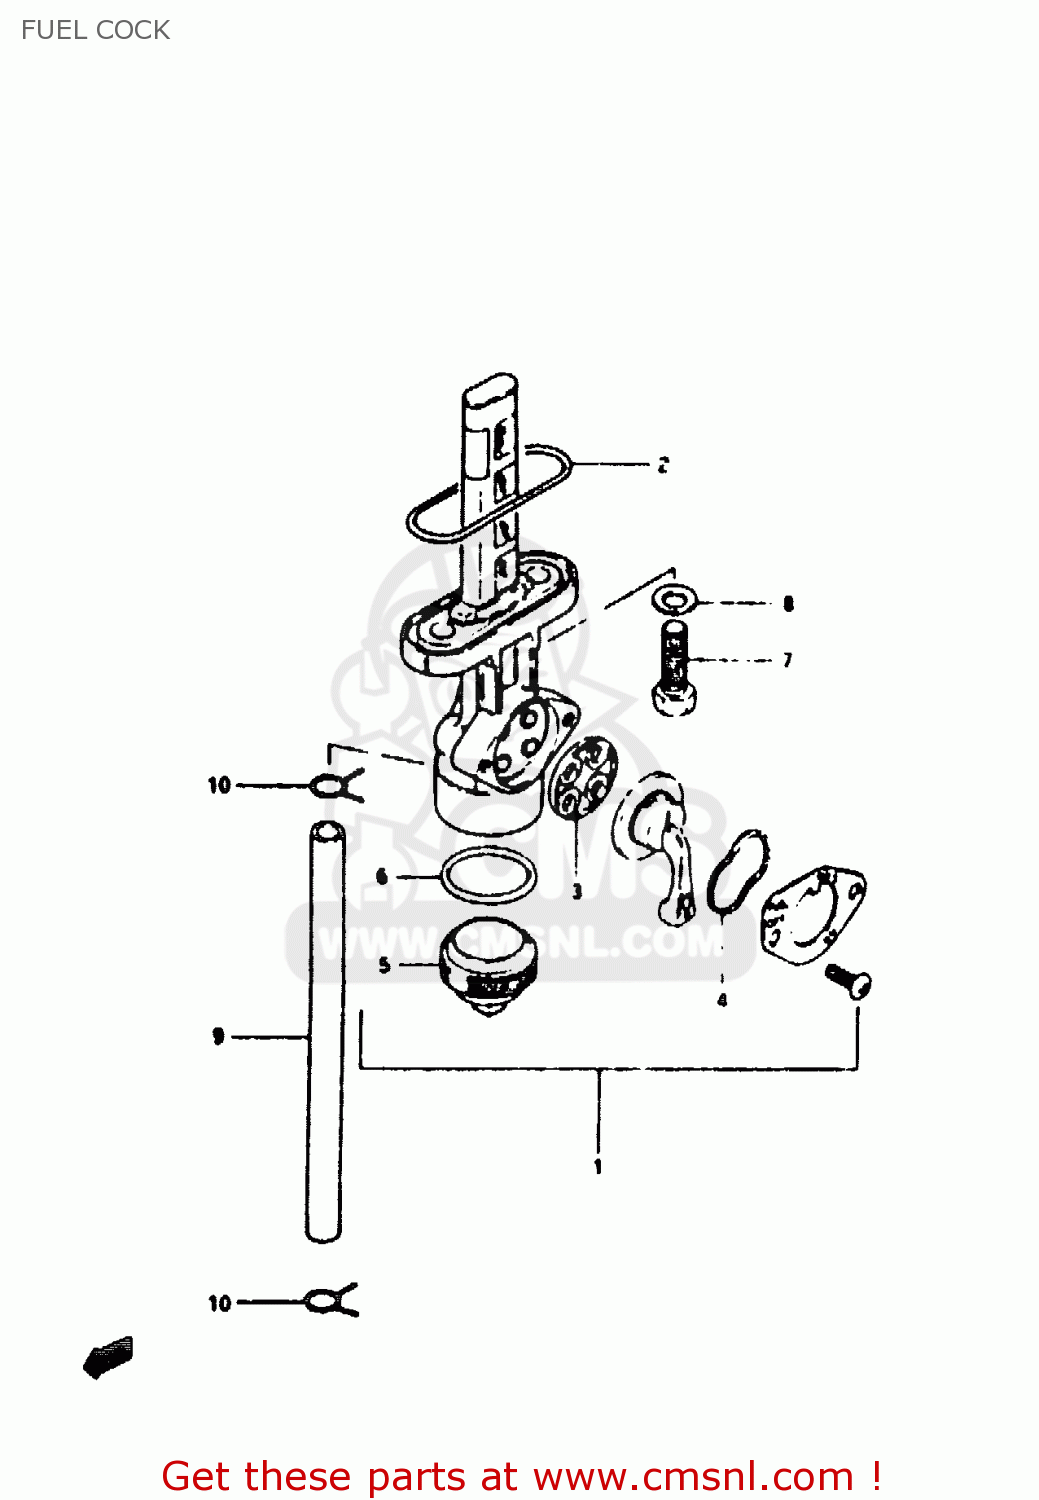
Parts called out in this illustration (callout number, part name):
1	COCK ASSEMBLY,FUEL
2	O RING,FUEL COCK
3	GASKET,LEVER (NAS)
4	WASHER,LEVER
5	CUP,FUEL COCK
6	GASKET,FILTER (NAS)
7	BOLT(6X20)
8	GASKET
9	HOSE
10	CLIP
